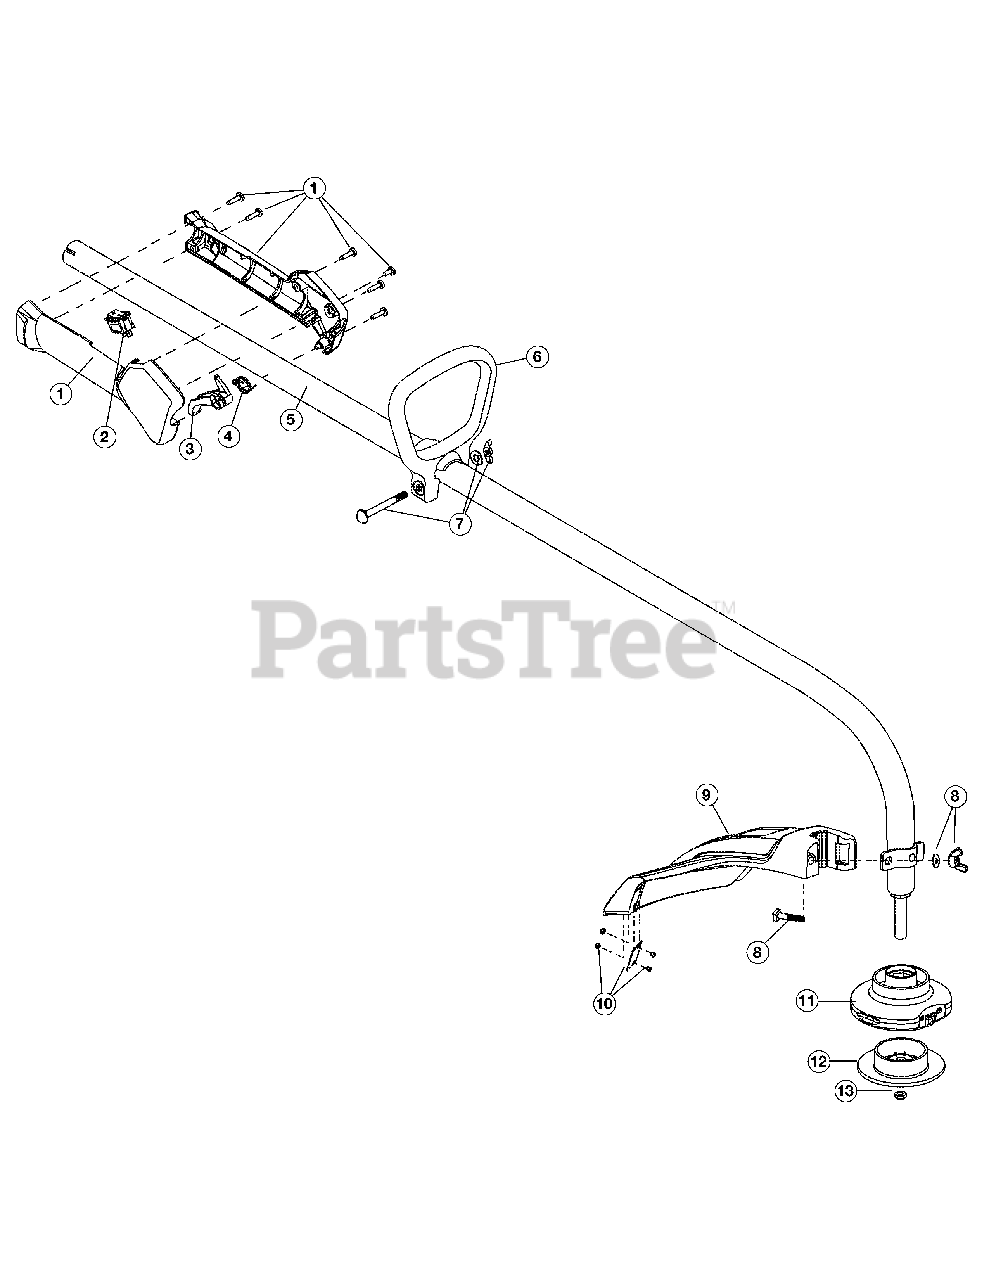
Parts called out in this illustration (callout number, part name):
1	Throttle Housing Assembly (includes 2-4)
3	Throttle Trigger
4	Throttle Trigger Spring
5	Drive Shaft Housing Assembly
6	D-Handle (includes 7)
7	Handle Hardware
8	Guard Mounting Hardware
9	Guard (includes 10)
10	Blade Assembly
11	Fixed Line Head Assembly (includes 12 & 13)
12	Glide Cap
13	Locknut
